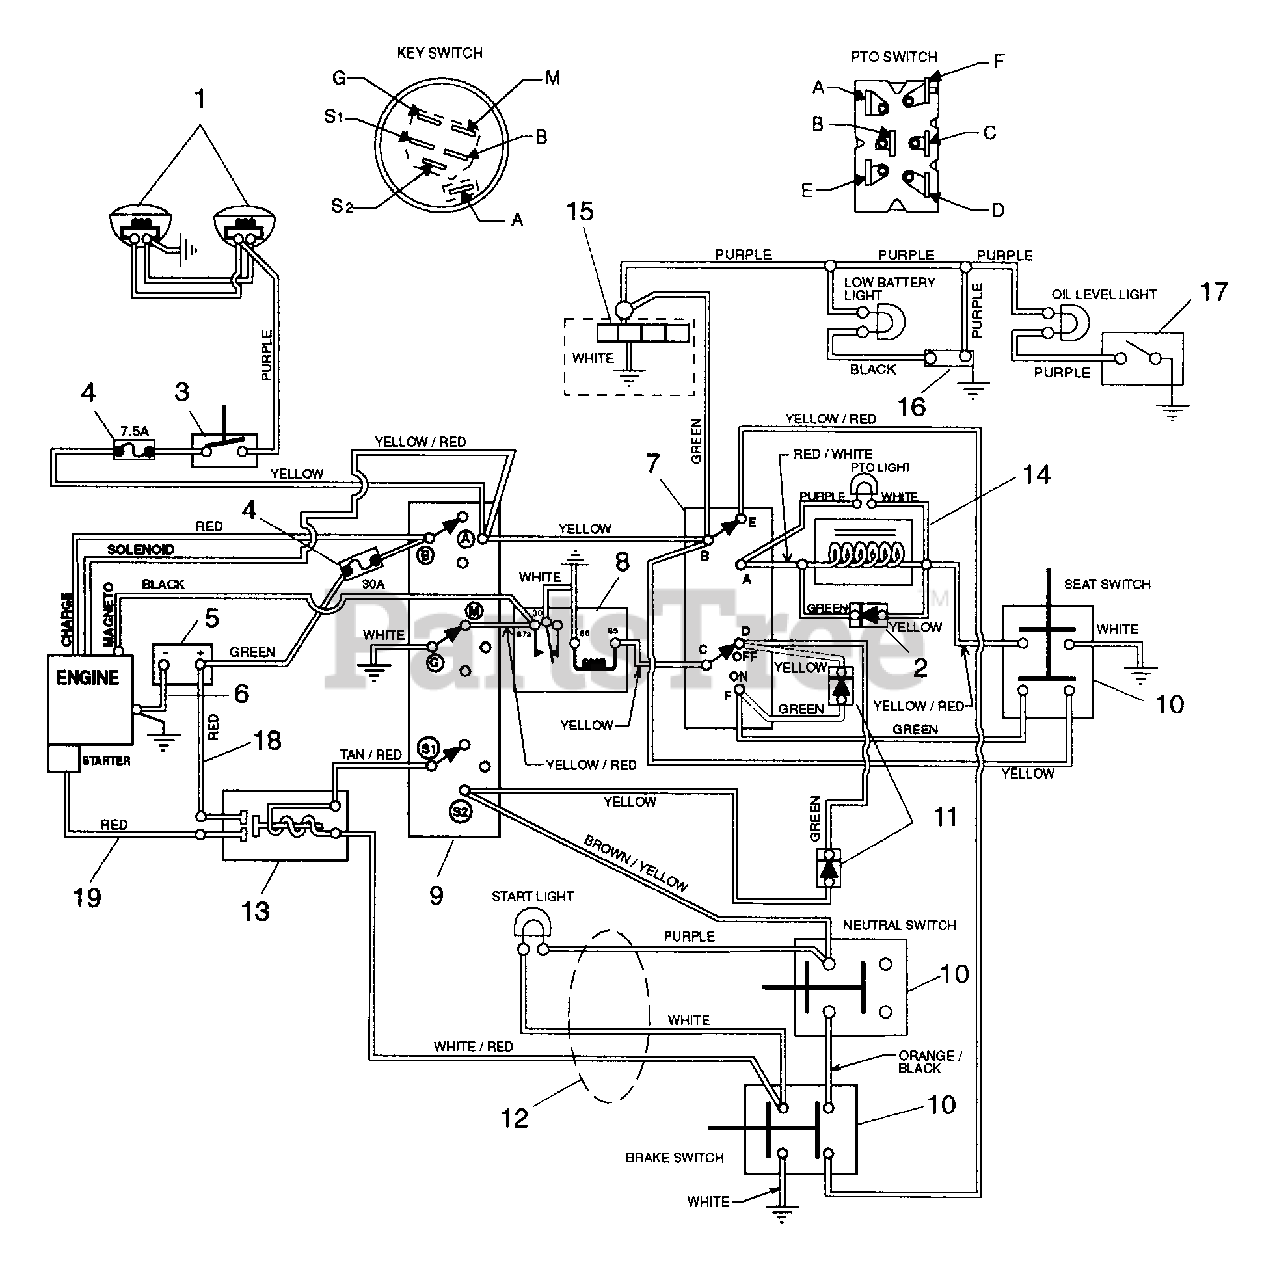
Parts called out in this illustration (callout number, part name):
1	HEADLIGHT- L.H.
1	HEADLIGHT- R.H.
2	DIODE & HOUSING
3	LIGHT SWITCH
4	7.5 Amp Fuse
4	30 Amp Fuse
5	BATTERY W/TUBE
6	GROUND CABLE .31X22.00X.31
7	SWITCH ASSEMBLY- PTO
8	RELAY
9	KEY SWITCH
10	SWITCH- DOUBLE POLE N.O./N.O.
11	MOLDED DIODE PLUG 1 AMP
12	WIRE HARNESS- YT160H
13	SOLENOID
14	ELECTRIC CLUTCH/BRAKE (3.4AMP)
15	HOURMETER
16	VOLTAGE SENSOR
17	OIL SENSOR- FASCO #0454-0513
18	START CABLE 22"
19	STARTER CABLE 6.75"
